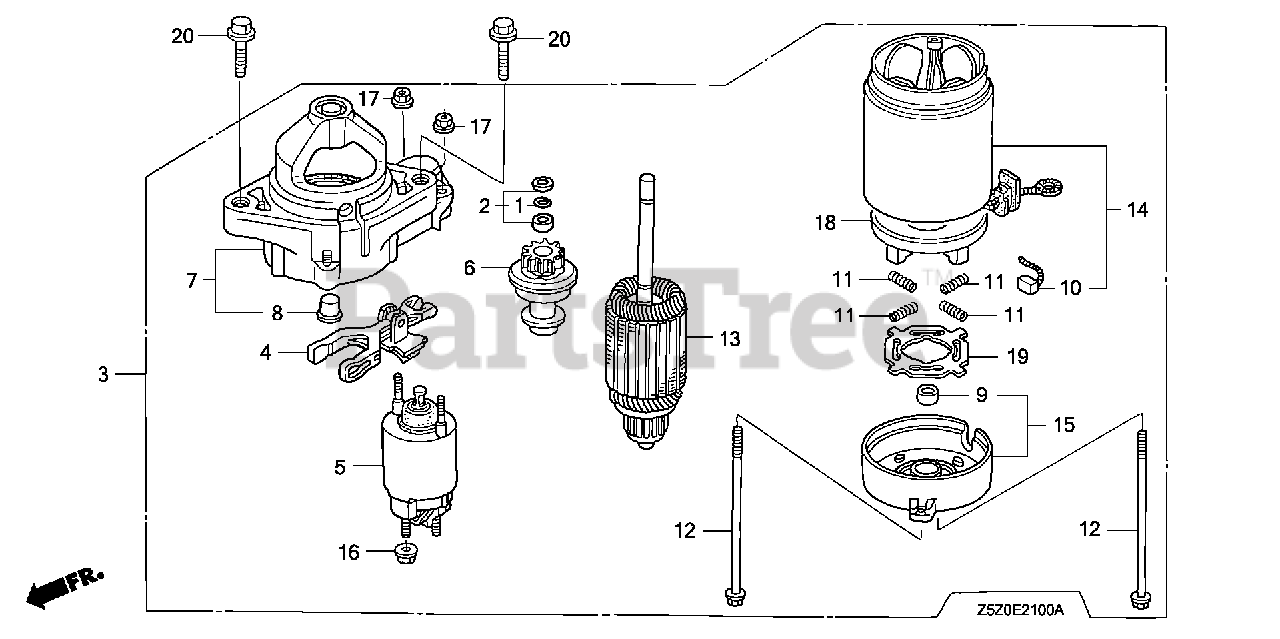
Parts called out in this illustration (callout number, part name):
1	RING, SNAP (DENSO)
2	COLLAR SET, CLUTCH STOP
3	STARTER MOTOR ASSY.
4	LEVER, PINION DRIVE
5	SWITCH ASSY., MAGNETIC
5	SWITCH ASSY., MAGNET
6	CLUTCH, OVERRUNNING
7	HOUSING, DRIVE SIDE
9	BEARING B
10	BRUSH
11	SPRING, BRUSH
12	BOLT, THROUGH
14	YOKE
15	FRAME, COMMUTATOR END
16	NUT, HEX. (8MM)
17	NUT, FLANGE (5MM)
18	HOLDER, BRUSH
19	INSULATOR, BRUSH HOLDER
20	BOLT, FLANGE (10X40)
